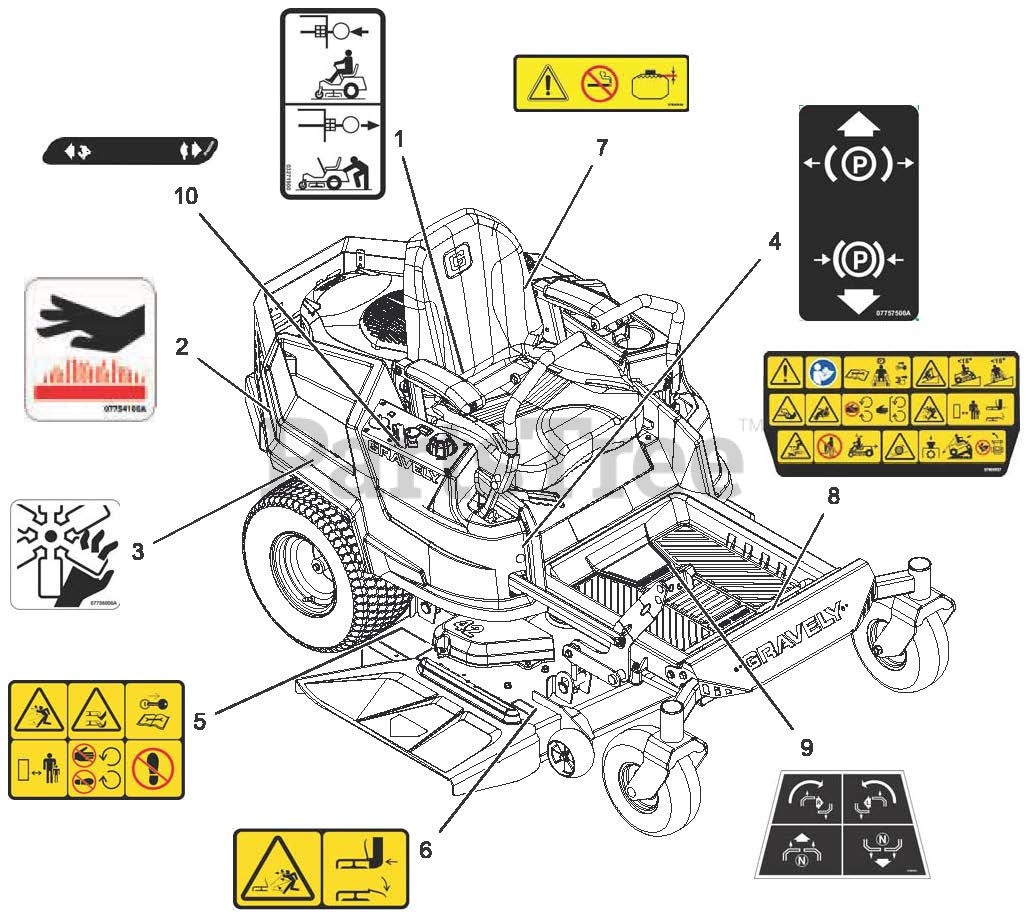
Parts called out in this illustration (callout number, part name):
1	DECAL, TRANSMISSION DEISCONNECT
2	DECAL, HOT SURFACE
3	DECAL, DANGER - FAN
4	DECAL, PARKING BRAKE LEVER
5	DECAL, SAFETY - MOWER DECK
6	DECAL, SAFETY - DECK GUARDING
7	DECAL, FUEL WARNING
8	DECAL, MAIN SAFETY-IKON ZTX
9	DECAL, STEERING
10	DECAL, DASH
